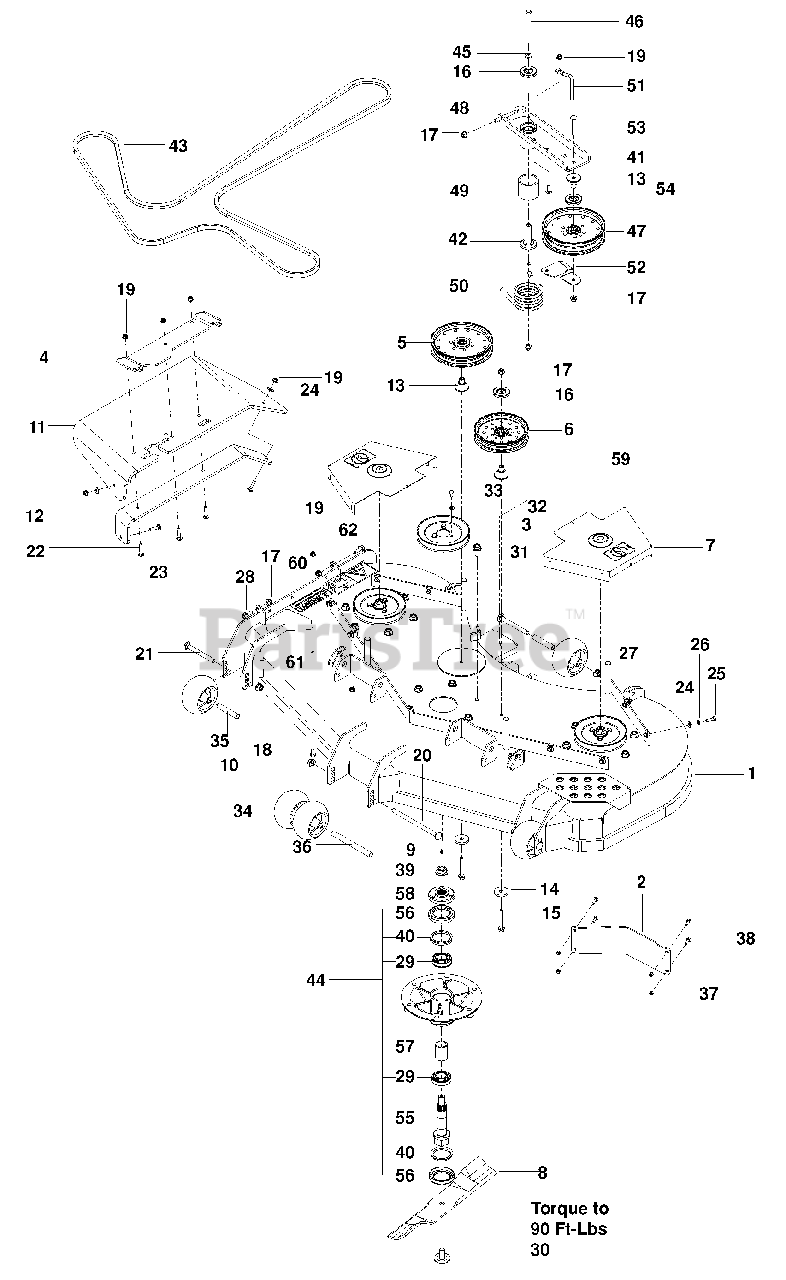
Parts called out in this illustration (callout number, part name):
1	DECK w/ SAFETY DECALS
2	BAFFLE, FLOW DIVERTER
4	BRACKET, CHUTE PIVOT
5	PULLEY, IDLER 7" NARROW
6	PULLEY, IDLER, 6"
7	SHIELD, BELT
8	BLADE, 21"
9	ZERK
10	NUT 1/2-13 HEX FLG NYLOC
11	CHUTE, DISCHARGE
12	BRACKET, CHUTE SUPPORT
13	BEARING, IDLER ARM
14	WASHER, HEAVY
15	SCREW 3/8-16 x 2 3/4HEX FLG
16	SHIELD, DUST
17	NUT 3/8-16 HEX FLG NYLOC
18	SCREW 5/16-18 x 3/4HEX FLG
19	NUT 5/16-18 HEX FLG NYLOC
20	BOLT 1/2-13 x 8 RD HD
21	BOLT 1/2-13 x 43/4RD HD
22	BOLT 5/16-18 x 1 1/2 RD HD
23	BOLT 5/16-18 x 1 1/4 RD HD
24	WASHER 5/16 STD FLT
25	BOLT 5/16-18 x 1 HEX HD
26	WASHER 5/16 SLW
27	RETAINER, U TYPE
28	SCREW 3/8-16 x 1 HEX FLG
30	BLADE BOLT
31	SCREW 1/2-13 x 1 HEX FLG
32	WASHER 5/16 DISC SPRING
33	BOLT 5/16-18 x 1/2 HEX NYLOC
34	ROLLER, GAUGE
35	TUBE, ROLLER AXLE
36	TUBE, ROLLER AXLE LONG
37	NUT 1/4-20 HEX NYLOC
38	BOLT 1/4-20 x 1 RD HD
39	NUT 3/4-16 FLG
41	IDLER ARM w/ BRGS, SPCR
42	BEARING, IDLER PIVOT
43	BELT, DECK Gasoline or Propane Models
44	SPINDLE ASSY
45	WASHER 3/8 THICK
46	BOLT 3/8-16 x 41/2 HEX GR 8
47	PULLEY, IDLER 7" WIDE
48	EYEBOLT 3/8 x 4
49	SPACER, IDLER PIVOT
50	SPRING, TORSION
51	KEEPER, BELT
52	GUIDE, BELT
53	BOLT 3/8-16 x 2 1/2 CARRIAGE
54	BOLT 5/16-18 x 1 RD HD
55	SHAFT, SPINDLE
56	CUP, DEBRIS
59	DECAL, NO STEP
60	DECAL, WARNING
61	DECAL, CPSC
62	DECAL, SEVERING
